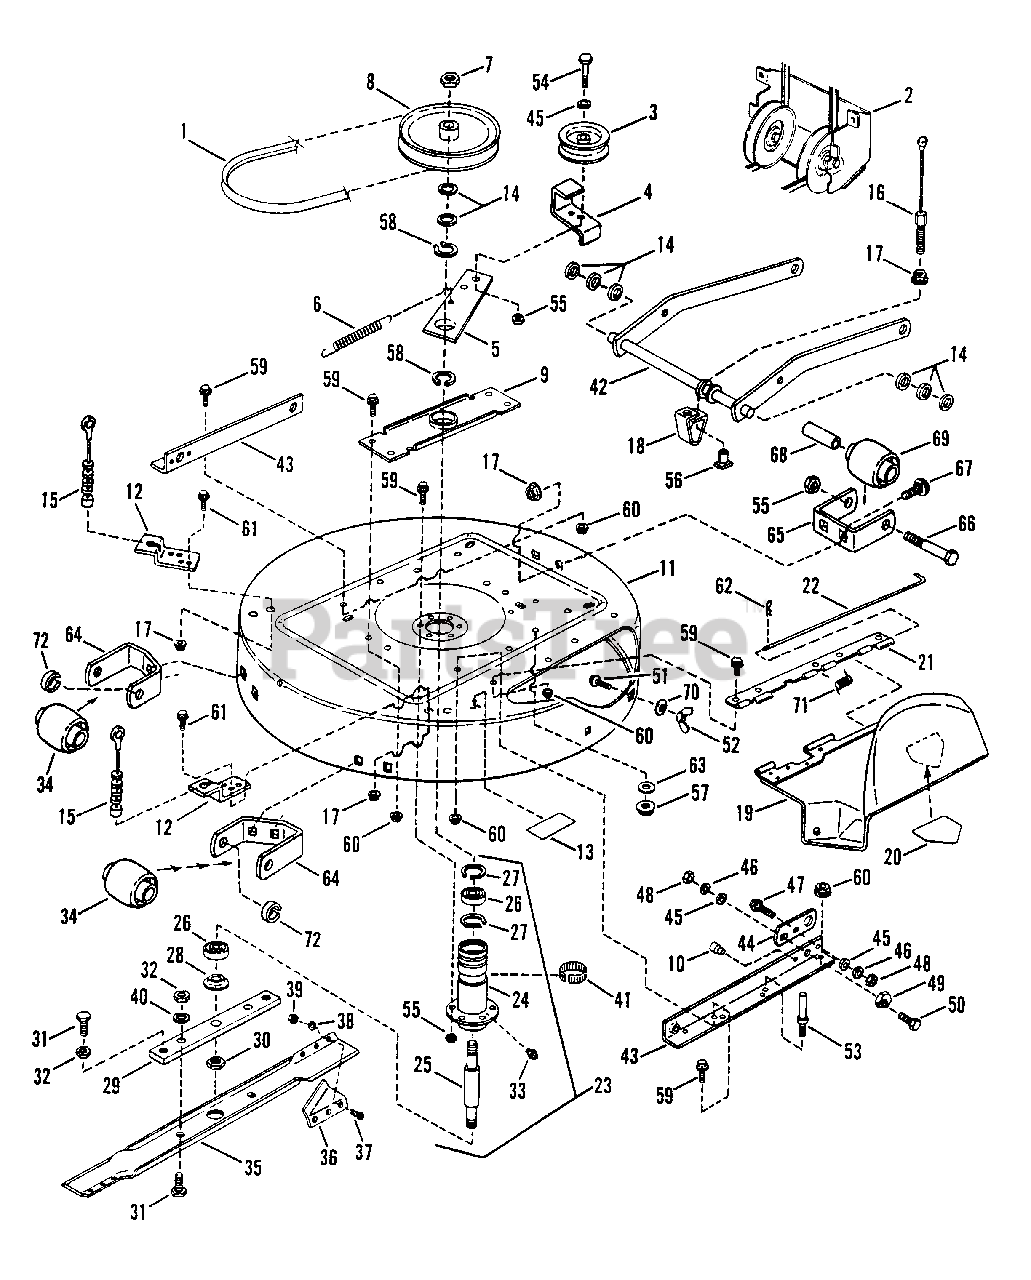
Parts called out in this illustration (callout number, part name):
1	BELT, 33" Drive
2	ASSEMBLY, Mule Drive
3	PULLEY, Idler, Flat, 4.12 O.D
4	GUIDE, Belt
5	ARM, Idler
6	SPRING, Belt Tension
7	NUT, 3/4-16 Hex Jam
8	PULLEY, 8" O.D.
9	BRACE, Spindle
10	BUMPER BUTTON
11	DECK, 33" Cutter
12	BRACKET, Rear Lift
13	DECAL-CAUTION, Deflector in Place
14	WASHER, Shim
15	CABLE, Rear Lift
16	CABLE, Front Lift
17	NUT, 5/16-18 Hex Flange Lock
18	BRACKET, Front Lift Hanger
19	ASSEMBLY, Deflector
20	DECAL-DANGER (Cut Finger)
21	HINGE, Side Chute
22	PIN, Hinge
23	ASSEMBLY, Spindle
24	HOUSING, Spindle
25	SPINDLE, 33" Mower Deck
26	BEARING, Spindle
27	RING, Retaining
28	WASHER, Spindle
29	HOLDER, Blade
30	NUT, 5/8-18 Hex Lock
31	SCREW, 1/2-20 x 1" Hex Head Cap (Grade 5)
32	JAM-NUT, 1/2-20 Hex
33	FITTING, Lube (Press fit for .187 hole-no ball)
34	WHEEL, Gage
35	BLADE, 33" Mower Deck
36	AIR-LIFT
37	SCREW, 5/16-24 x 11/16" Machine
38	WASHER, 5/16-24 Internal Tooth Lock
39	NUT, 5/16-24 Hex
40	WASHER, 1/2 Internal Tooth Lock
41	RING, Tolerance
42	WELDMENT, Front Lift Arm
43	RAIL, Lift Arm
44	LINK-ADJUSTMENT
45	WASHER, 3/8 SAE
46	WASHER, 3/8 Split Lock
47	BOLT, 3/8-16 x 3/4" Carriage
48	NUT, 3/8-16 Hex
49	RING, Adjustment
50	SCREW, 3/8-16 x 1" Hex Head Cap
51	BOLT, 5/16-18 x 3/4" Short Neck Carr.
52	WING-NUT, 5/16-18
53	STUD, Deck Stop
54	SCREW, 3/8-24 x 1 1/2" Hex Head Cap
55	NUT, 3/8-24 Hex Lock
56	T-NUT, 5/16-18
57	NUT, 3/8-24 Hex
58	RING, 2" External Retaining
59	BOLT, 3/8-16 x 3/4" Hex Flng. Lock
60	NUT, 3/8-16 Hex Flange Lock
61	BOLT, 5/16-18 x 1/2" Hex Flange Lock, (Grade 5)
62	HAIR-PIN
63	WASHER, 3/8 Internal Tooth Lock
64	BRACKET, Gage Wheel (Rear)
65	BRACKET, Gage Wheel (Front)
66	SCREW, 3/8-24 x 3 3/4" Hex Hd. Cap
67	BOLT, 5/16-18 x 1/2" Short Neck Carr.
68	SPACER
69	WHEEL, Gage
70	WASHER, 5/16 Flat
71	SPRING, Hinge
72	RING
